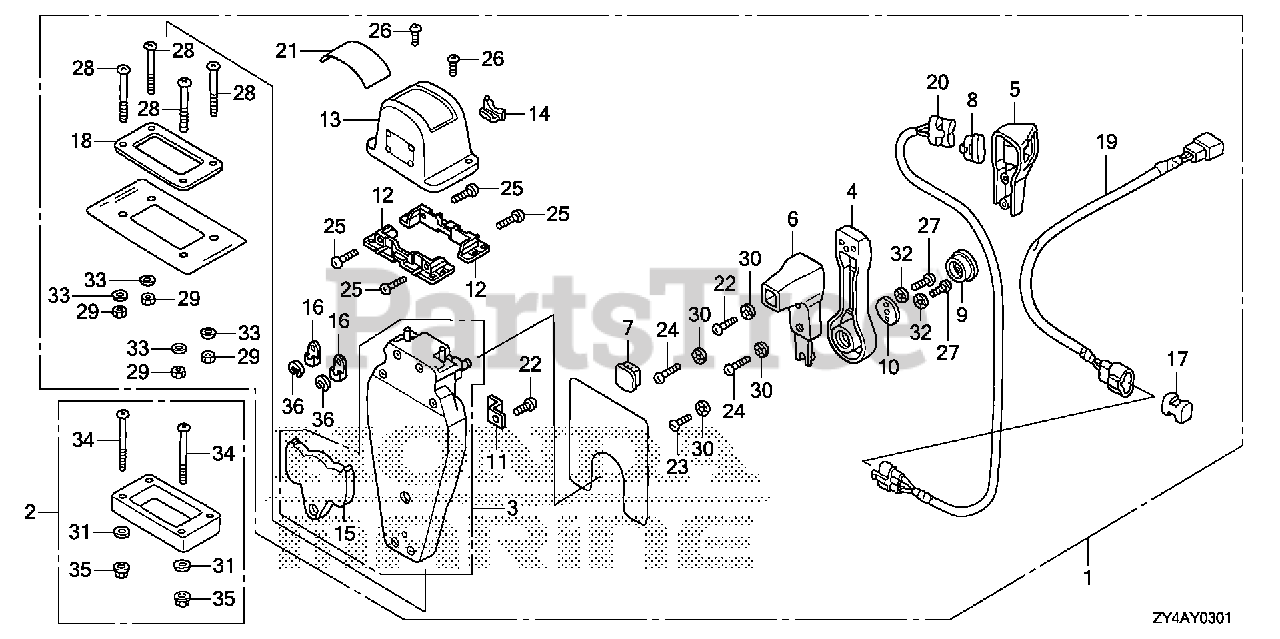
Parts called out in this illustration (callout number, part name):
1	BOX KIT, REMOTE CONTROL (TOP MOUNT SINGLE)(L)
3	HOUSING ASSY., R. (INNER) (TOP MOUNT)
4	HANDLE, REMOTE CONTROL
5	COVER, R. GRIP
6	GRIP, REMOTE CONTROL HANDLE
7	CAP, GRIP
8	CAP, SWITCH
9	BUTTON, THROTTLE
10	PLATE, HANDLE
11	PLATE, CABLE CLAMP
12	BRACKET, REMOTE CONTROL HOUSING
13	HOUSING, REMOTE CONTROL BOX
14	HOUSING, LEAD
15	PLATE, DWELL
16	TERMINAL, CABLE
17	SPACER, CABLE CLAMP
18	GASKET, SINGLE
19	SUB-HARNESS ASSY., POWER TRIM-TILT (B)
20	SWITCH ASSY., POWER TRIM-TILT (B)
21	MARK, REMOTE CONTROL (SINGLE)
22	SCREW, PAN (5X16)
23	SCREW, PAN (5X10)
24	SCREW, PAN (5X20)
25	SCREW, PAN (5X18)
26	SCREW, PAN (4X10)
27	SCREW, PAN (6X18)
28	SCREW, PAN (5X40)
29	NUT, HEX. (5MM)
30	WASHER, LOCK (5MM)
32	WASHER, LOCK (6MM)
33	WASHER, PLAIN (5MM)
36	E-RING (6MM)
